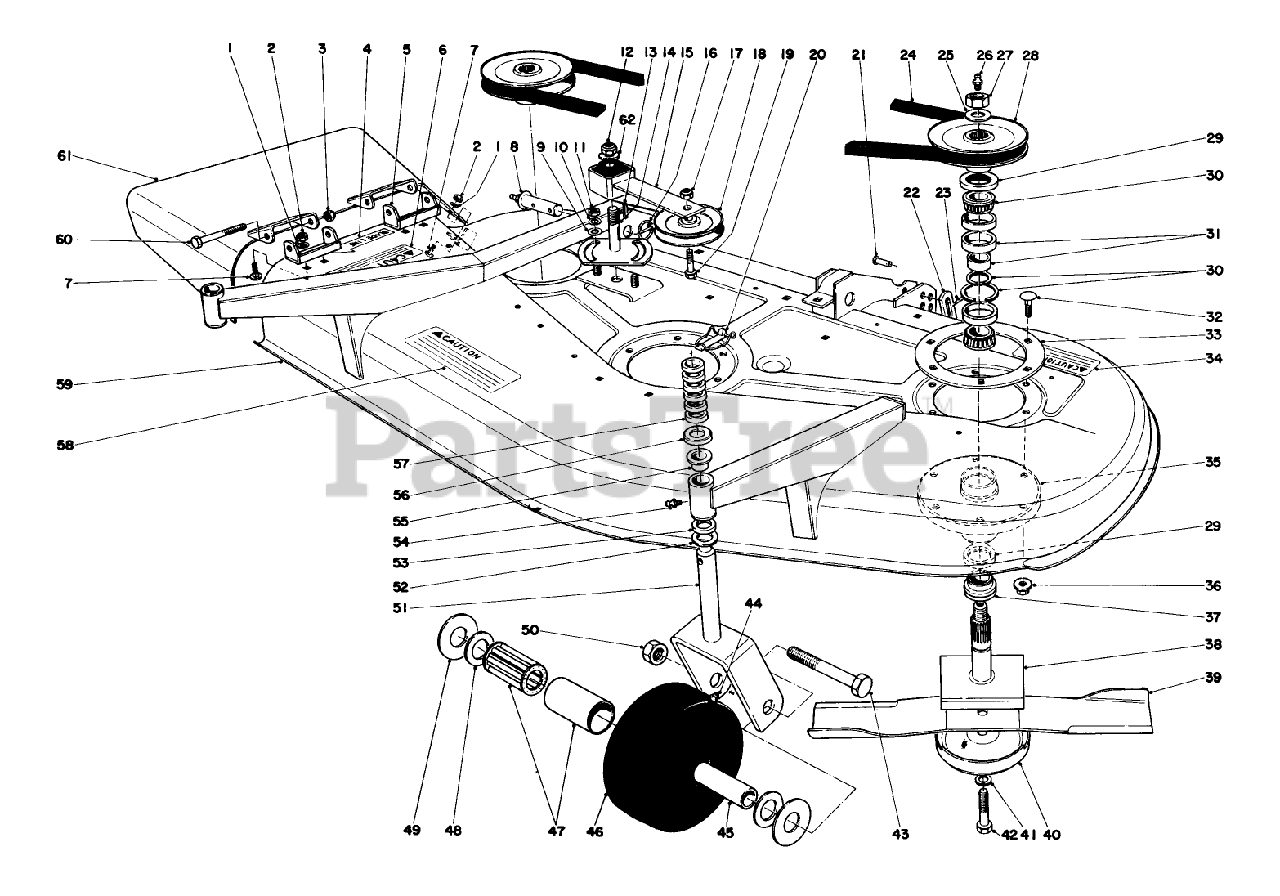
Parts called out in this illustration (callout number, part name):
1	WASHER-LOCK
2	NUT-HEX
3	NUT-HEX
4	DECAL - BLADE LINE
5	Bracket-Pivot
6	DECAL-CAUTION, DEFLECTOR
7	SCREW-CARR
8	PIVOT PIN WA RO
9	WASHER-FLAT
10	WASHER-LOCK
11	NUT-JAM
12	NUT-LOCK, NI
13	KEY-SQUARE
14	PLATE-IDLER
15	IDLER ARM ASM
16	PIN-LYNCH
17	NUT-HEX
18	Idler Pulley
19	SCREW-HH
20	PIN-LYNCH
21	PIN-CLEVIS
22	LIFT BRKT LINKAGE R
23	PIN-HAIR
24	V-BELT
25	WASHER
26	FITTING-GREASE
27	NUT-HEX
28	PULLEY AND HUB ASM
29	SEAL-OIL
30	BEARING ASM
31	SPACER-SET, MATCHED
32	SCREW-CARR
33	SUPPORT-DECK, RING
34	DECAL-CAUTION, BLADE
35	Housing-Spindle
36	NUT-HF
37	SPACER
38	SHAFT
39	Blade
40	Cup-Scalp
41	WASHER-LOCK
42	Capscrew
43	SCREW-HH
44	GREASE FITTING
45	SPANNER BUSHING
46	WHEEL
47	ROLLER BEARING
48	BEARING RETAINER
49	THRUST WASHER
50	NUT-LOCK
51	Castor Fork
52	WASHER-THRUST
53	SPACER
54	FITTING-GREASE
55	Bushing
56	CASTOR SLINGER
57	SPACER 1/2 IN
58	Decal-Caution
59	52 IN DECK WA RO
60	SCREW-HH
61	DEFLECTOR WA R
62	WASHER-FLAT
